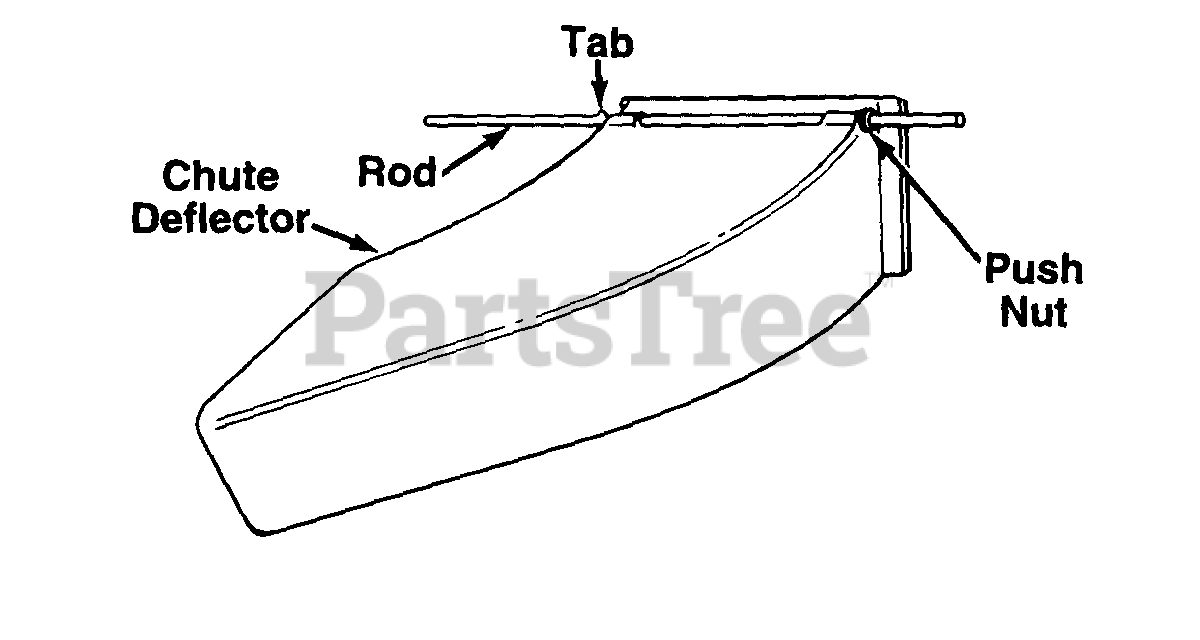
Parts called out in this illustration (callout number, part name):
1	Deflector
3	Push Speed Nut
4	Push Cap (19" Mowers)
